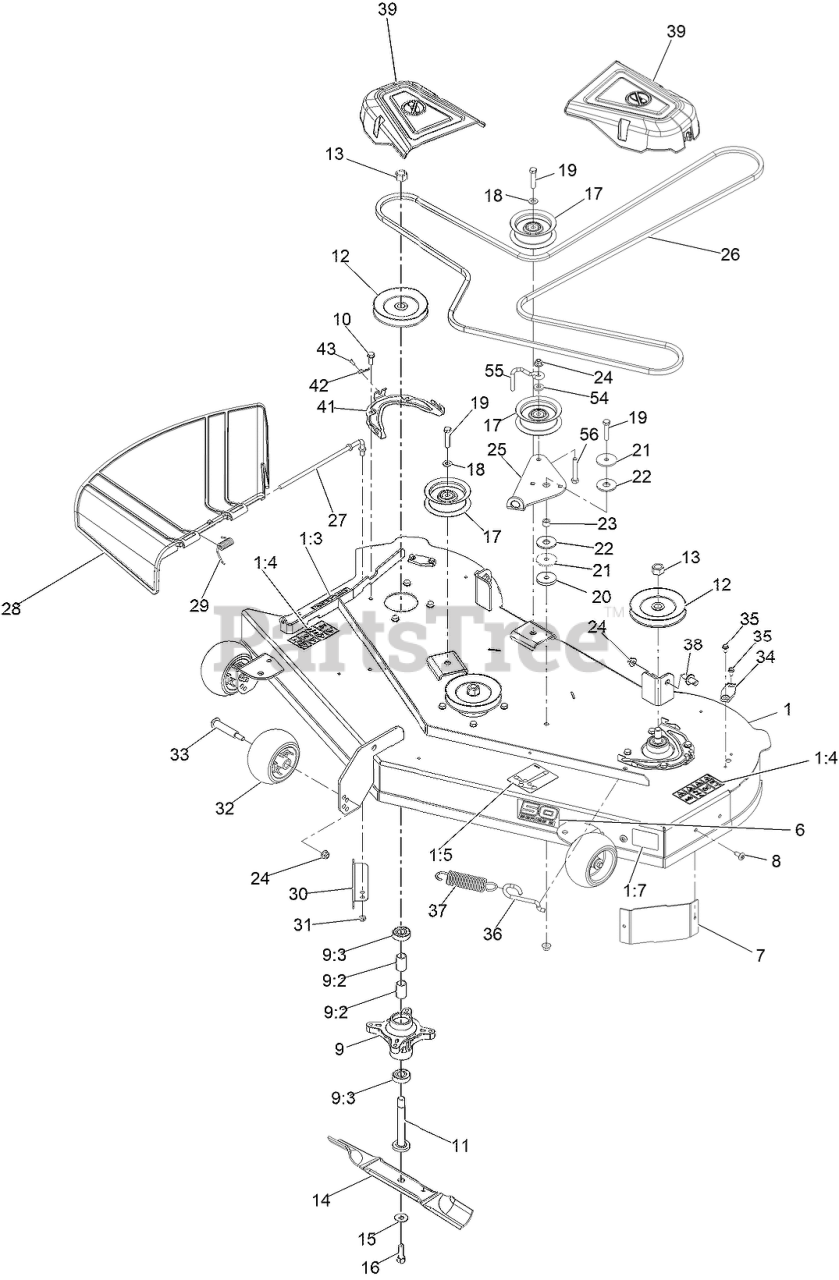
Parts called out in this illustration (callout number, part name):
1	50 INCH DECK AND DECAL ASM
1:3	DECAL-DANGER
1:4	DECAL-DANGER, DECK
1:5	DECAL-ROUTING, BELT
1:7	DECAL-SCALP, ANTI
6	Decal-50 Series 2
7	BAFFLE-CORNER
9	SPINDLE ASM
9:3	BEARING-BALL
10	SCREW-TAPTITE
11	SHAFT-SPINDLE
13	NUT-HEX
14	BLADE-HI LIFT
15	WASHER-BELLEVILLE
16	SCREW-HH
17	PULLEY-IDLER, FLAT
18	WASHER-FLAT
19	SCREW-HH
20	WASHER-PLAIN
21	WASHER-REBOUND
22	WASHER-FRICTION, COMPOSIT
24	NUT-HF, NI
25	Arm-Idler
26	V-BELT
27	ROD-PIVOT
28	DEFLECTOR-DISCHARGE
29	SPRING-TORSION
30	BAFFLE-CUTOFF
32	ROLLER-SCALP, ANTI
33	BOLT-SHOULDER
34	COVER-WASHOUT PORT
35	SCREW-HWH
36	Hook-Return Spring
37	SPRING-EXTENSION
38	PIN-DECK
39	COVER-BELT
41	BRACKET-COVER, BELT
42	PIN-HAIR
54	SPACER-HUB, BLOWER
55	Belt Guide - Idler
56	SCREW-HH
